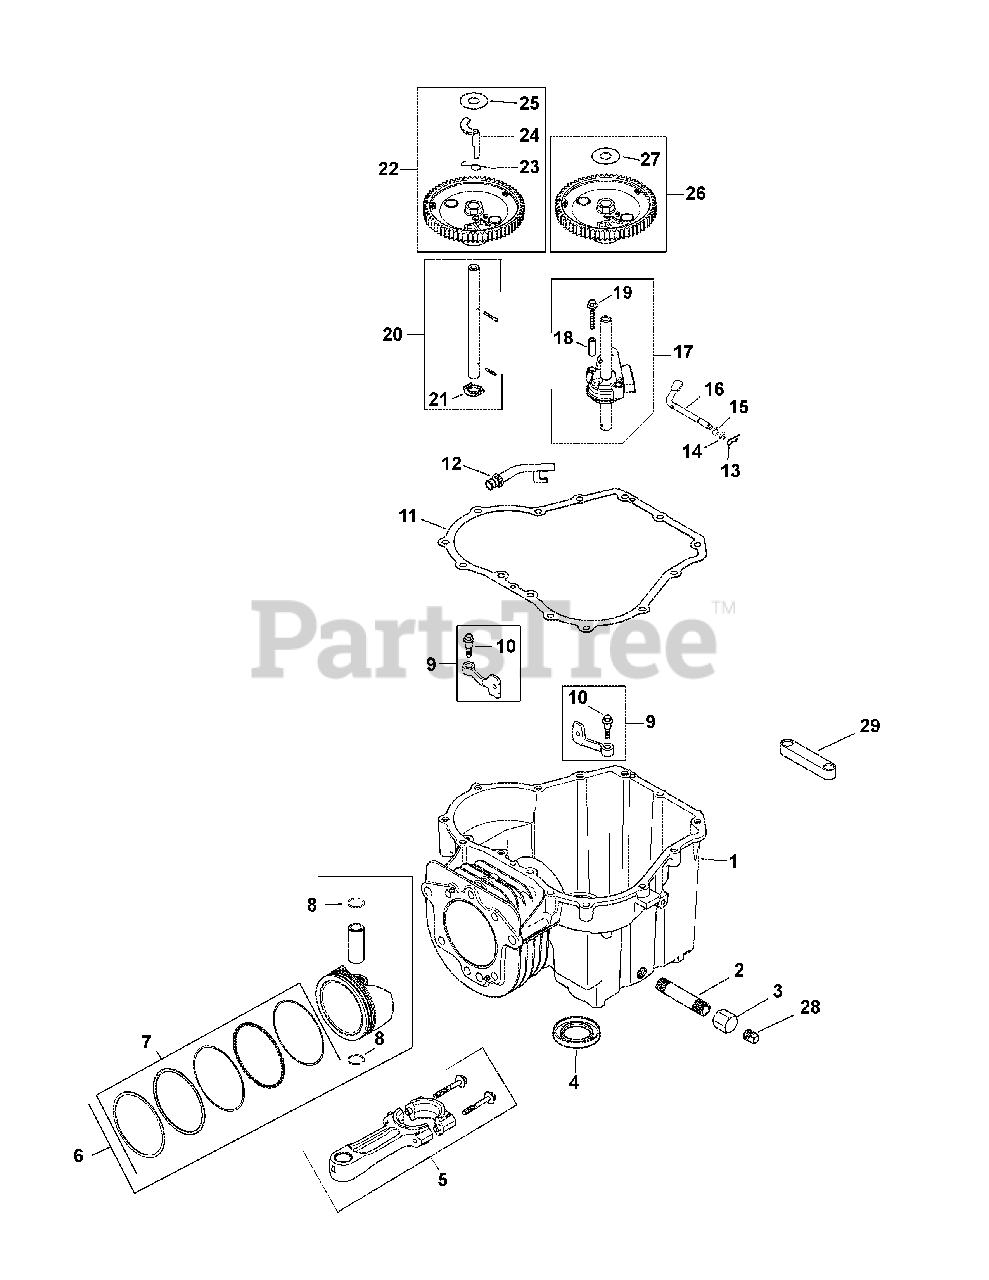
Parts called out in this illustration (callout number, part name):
1	Crankcase
2	Fuse Block
3	Fuse Block
4	Oil Seal
5	Connecting Assembly Rod
6	Piston W/ Ring Set Kit, 94mm
7	Ring Set (94mm)
8	Piston Pin Retainer
9	Cam Lever Ass. Kit
10	Shd. Thd. Frm. Screw, M6 X 1 X 26
11	Fuse Block
12	Drainback Tube
13	Hitch Pin Clip
14	Flat Washer, 6 Mm
15	Flat Washer, 1.4
16	Governor Cross Shaft
17	Oil Pump Assembly Kit
18	Oil Pump Screw Spacer
19	Oil Pump Screw
20	Cam Center Shaft Kit
21	Thrust Washer
22	Camshaft Assembly Kit
24	Acr. Weight
25	Thrust -Acr. Washer
26	Camshaft Assembly Kit
27	Thrust -Acr. Washer
28	Square Head Pipe Plug, 3.8
29	Fuse Block
30	Fuse Block
31	Fuse Block
32	Fuse Block
33	Fuse Block
